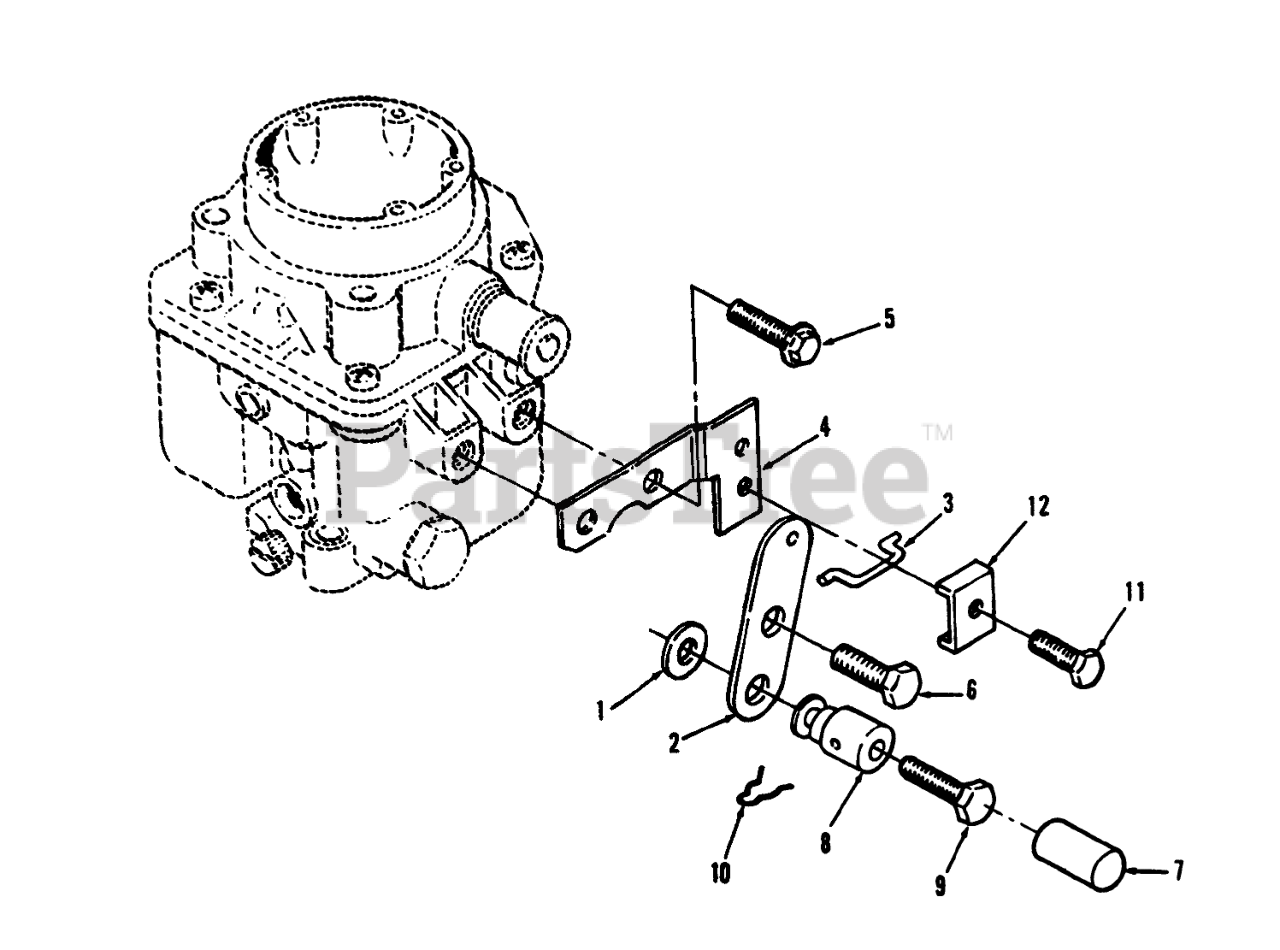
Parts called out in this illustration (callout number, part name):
1	Washer
2	Lever
3	Link
4	Bracket
5	Bolt
6	MACHINE SCREW
8	Swivel
9	Bolt
10	PIN-COTTER
11	SCREW-TAPPING
